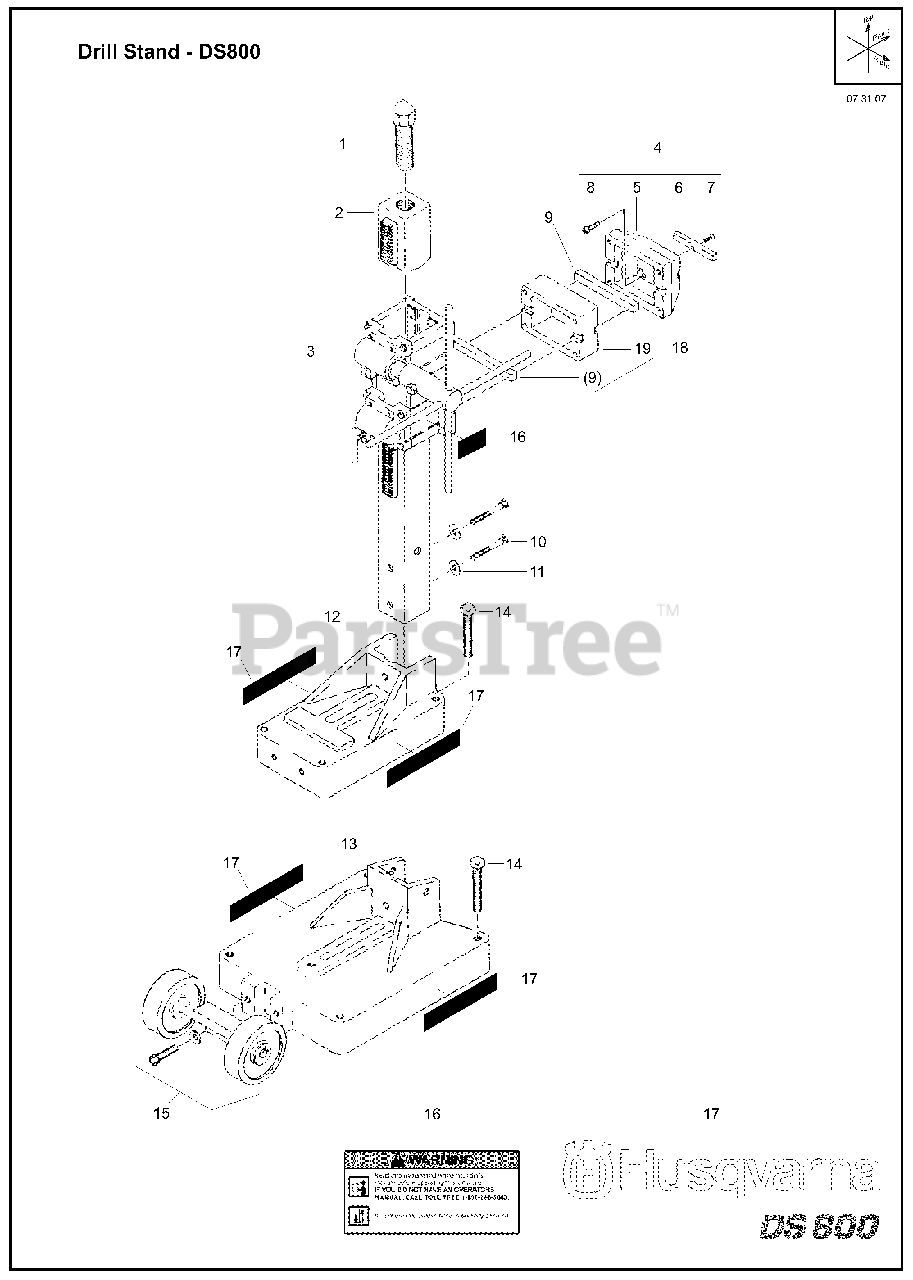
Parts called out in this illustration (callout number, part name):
1	Screw, Ceiling Jack, 1-1/4"-7NC
2	Column w/ Rack - 2-7/8" Sq x 42"
3	Carriage, Side, DS800 - compl
3	Carriage, Roller, DS800 - compl
4	Adapter, Motor Mtg, DS 800 - compl
5	Adapter, Motor Mtg, DS800
6	Key, .375" Sq x 3.625
7	Screw, Flat Hd, 8-32 x 3/4"
8	Capscrew, Soc Hd 1/4-20 x 1"
8	Capscrew, Soc Hd 1/4-28 x 1"
8	Capscrew, Soc Hd M8-1.25 x 25
9	Key, .500" Sq x 6
9	Key, .50 Sq x 5.88"
10	Capscrew, Hex Hd 5/8-11 x 4"
11	Washer, Flat 5/8"
12	Base, Small, DS800 - Husq Orange
13	Base, Combination, DS800 - Husq Orange
14	Capscrew, Sq Hd 3/4-10 x 4"
15	Axle & Wheels - compl
16	Decal, WARNING - Secure / Read
17	Decal, HUSQVARNA DS800
18	Kit, 2" Spacer Block, DS800
19	Block, 2" Spacer, Husq Orange
